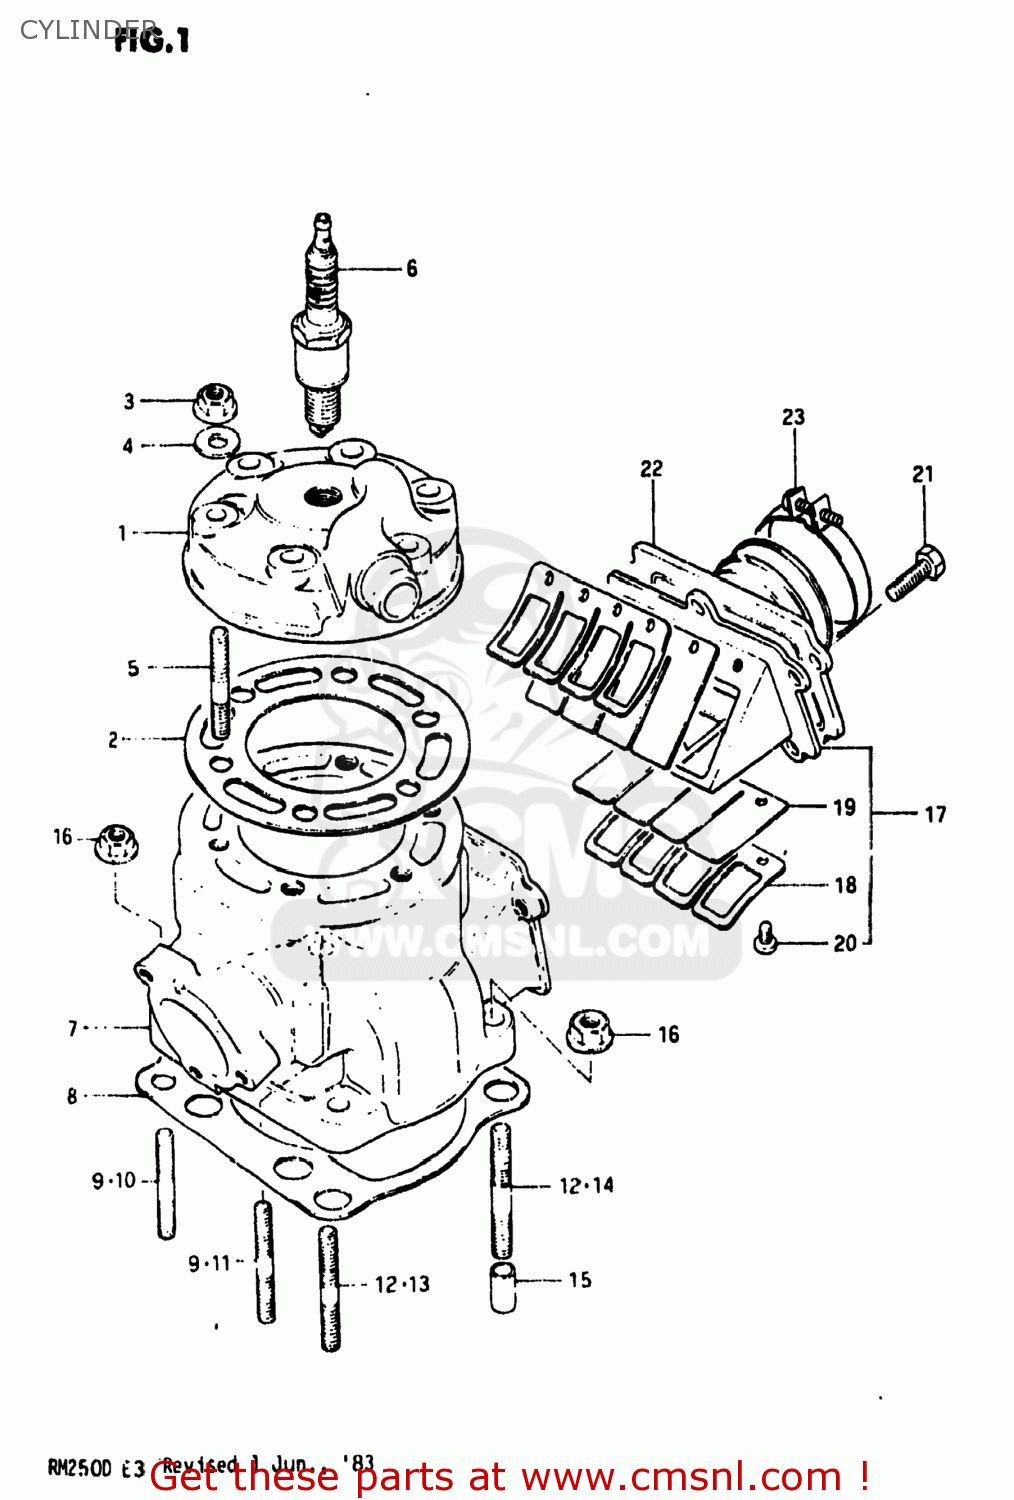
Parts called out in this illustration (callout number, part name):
1	HEAD,CYLINDER
2	GASKET,CYLINDER HEAD
3	NUT 8MM
4	WASHER (8.5X19X2.3)
5	STUD
6	PLUG,SPARK(NGK B-8EN)
7	CYLINDER
8	GASKET,CYLINDER (MCA)
9	STUD
10	BOLT,STUD
11	BOLT,STUD
12	STUD
13	BOLT,STUD
14	STUD
15	PIN
16	NUT 8MM
17	VALVE ASSEMBLY,REED
18	STOPPER,REED VALVE
19	VALVE,REED
20	SCREW
21	BOLT
22	PIPE,INTAKE
23	CLAMP
